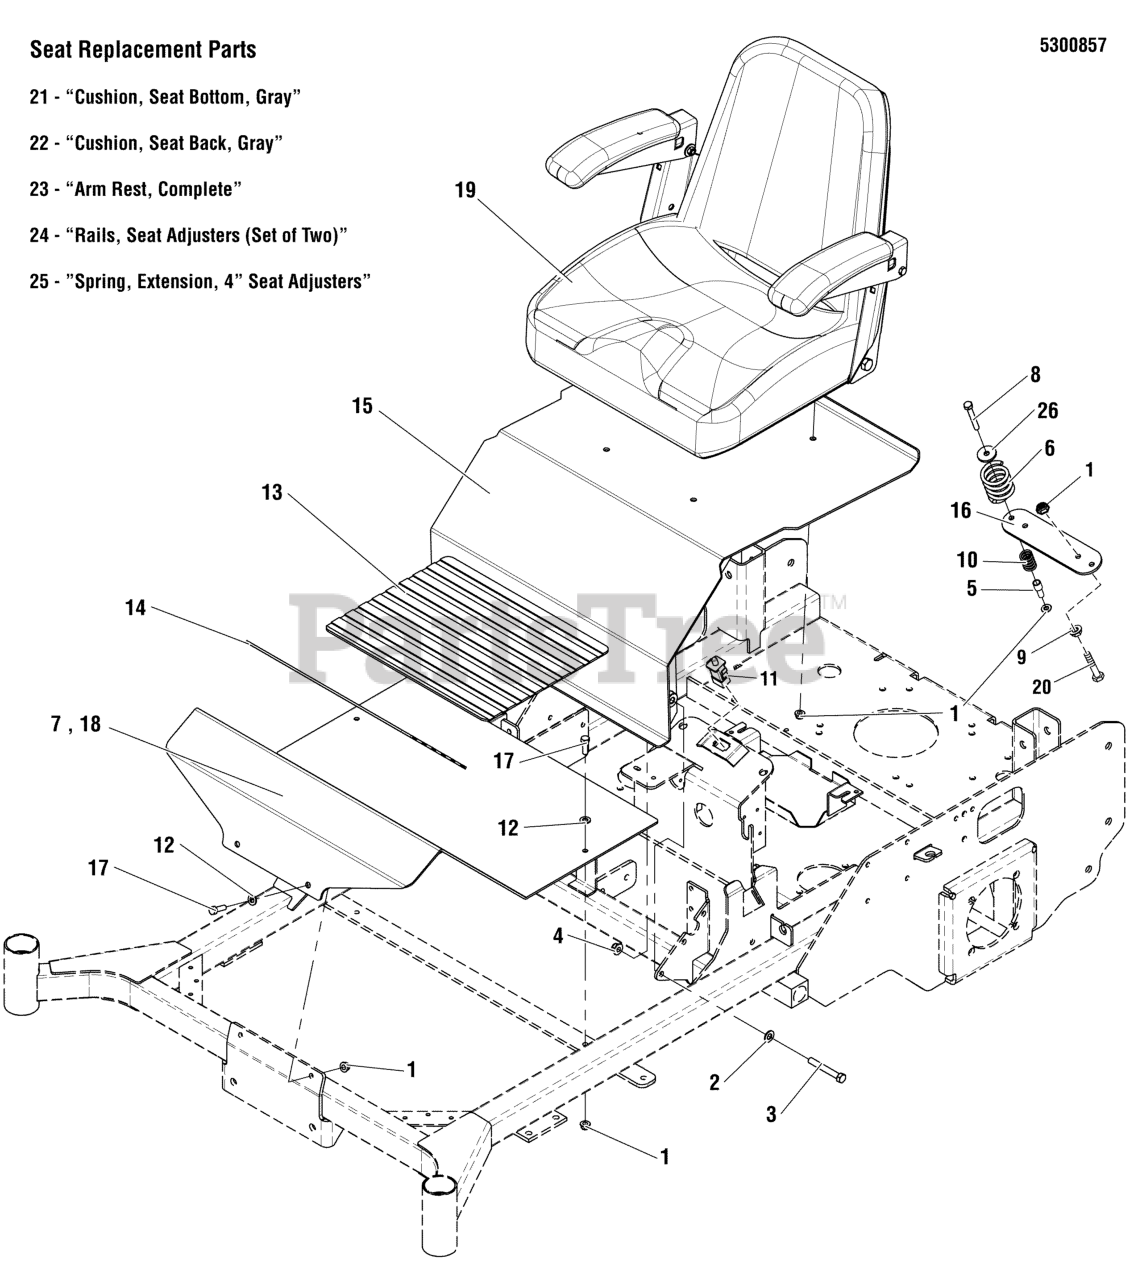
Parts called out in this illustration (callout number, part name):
1	NUT, 5/16-18 HEX NYLOCK FLANGE
2	WASHER, 3/8 SAE
3	BOLT, 3/8-16 X 2, GD5, CZ
4	NUT, 3/8-16 HEX NYLOCK FLANGE
5	SPACER, .328 ID X .66, YZ
6	SPRING, SEAT SUPPORT
7	PLATE, FLOOR PAN, SNP 61
8	BOLT, 5/16-18 X 2-1/4" GD5 YZ
9	NUT, 5/16-18 HEX SERRATED FLANGE (SMALL)
10	SPRING, COMP 720ID X 1.310LG X .118WIRE
11	SWITCH, PLUNGER, NO/NO SNAP IN
12	WASHER, 5/16" SAE
13	SAFETY WALK, 11.50 X 19.00
14	SAFETY WALK, 10.00 X 19.00
15	WELD, SEAT PLATE - RED
16	PLATE, SEAT SWITCH - RED
17	BOLT, 5/16-18 X 1 GD5 YZ
18	PLATE, FLOOR PAN, S200X - SNAPPER RED
20	BOLT, 5/16-18 X 1-1/4 GD5 YZ
25	SPRING, EXTENSION, SEAT ADJUSTMENT (YEL OR BLK)
26	WASHER, .34 X 1.25 X 10 GA
